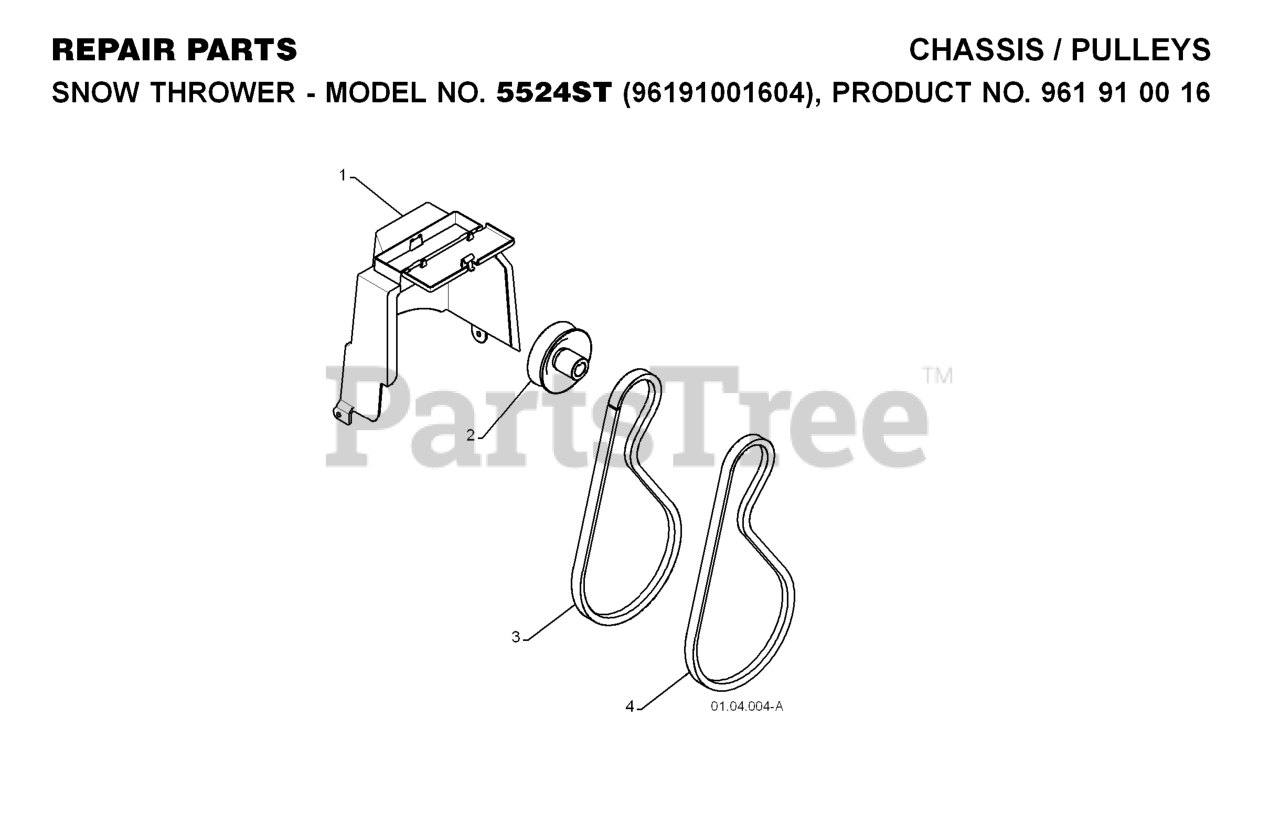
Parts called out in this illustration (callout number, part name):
1	COVER.ASM.BELT/STORAGE
2	PULLEY, ENGINE IMPELLER DRIVE
3	V-BELT TRACTION 34.25
4	BELT.V.IMPELLER
